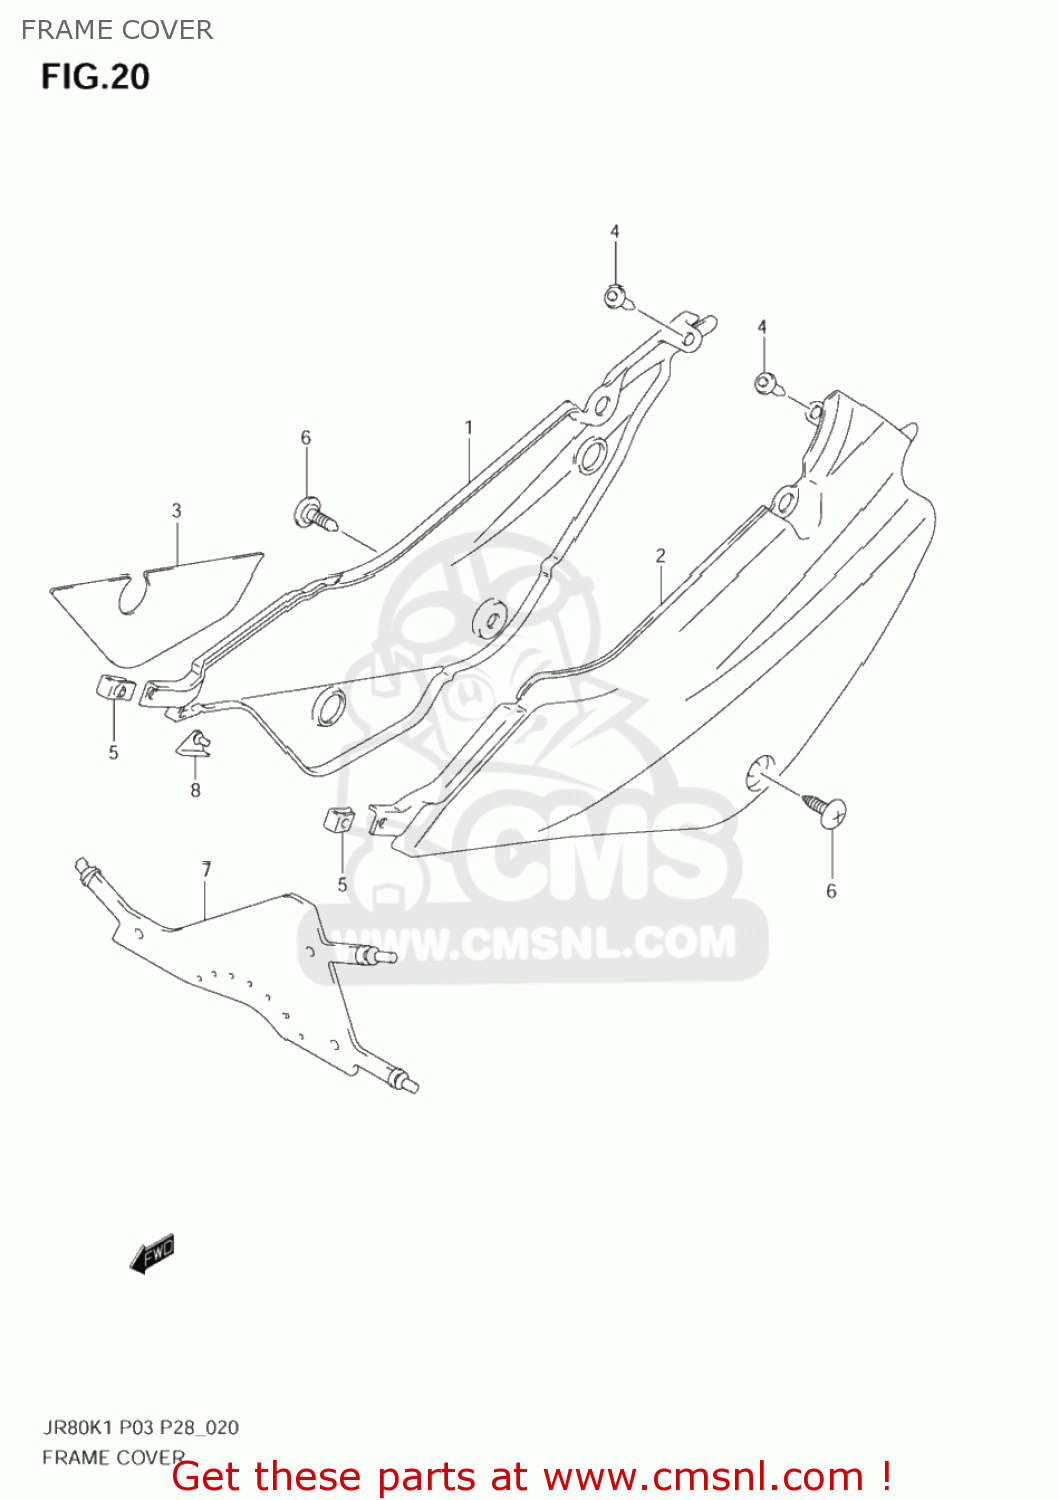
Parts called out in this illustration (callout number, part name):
1	COVER,FRAME,R(WHITE)
2	COVER,FRAME,L(WHITE)
3	TAPE,FRAME COVER,R
4	CLIP(BLACK)
5	NUT
6	SCREW(6X16)
7	MUDGUARD,FRAME COVER
8	CUSHION,FRAME COVER
